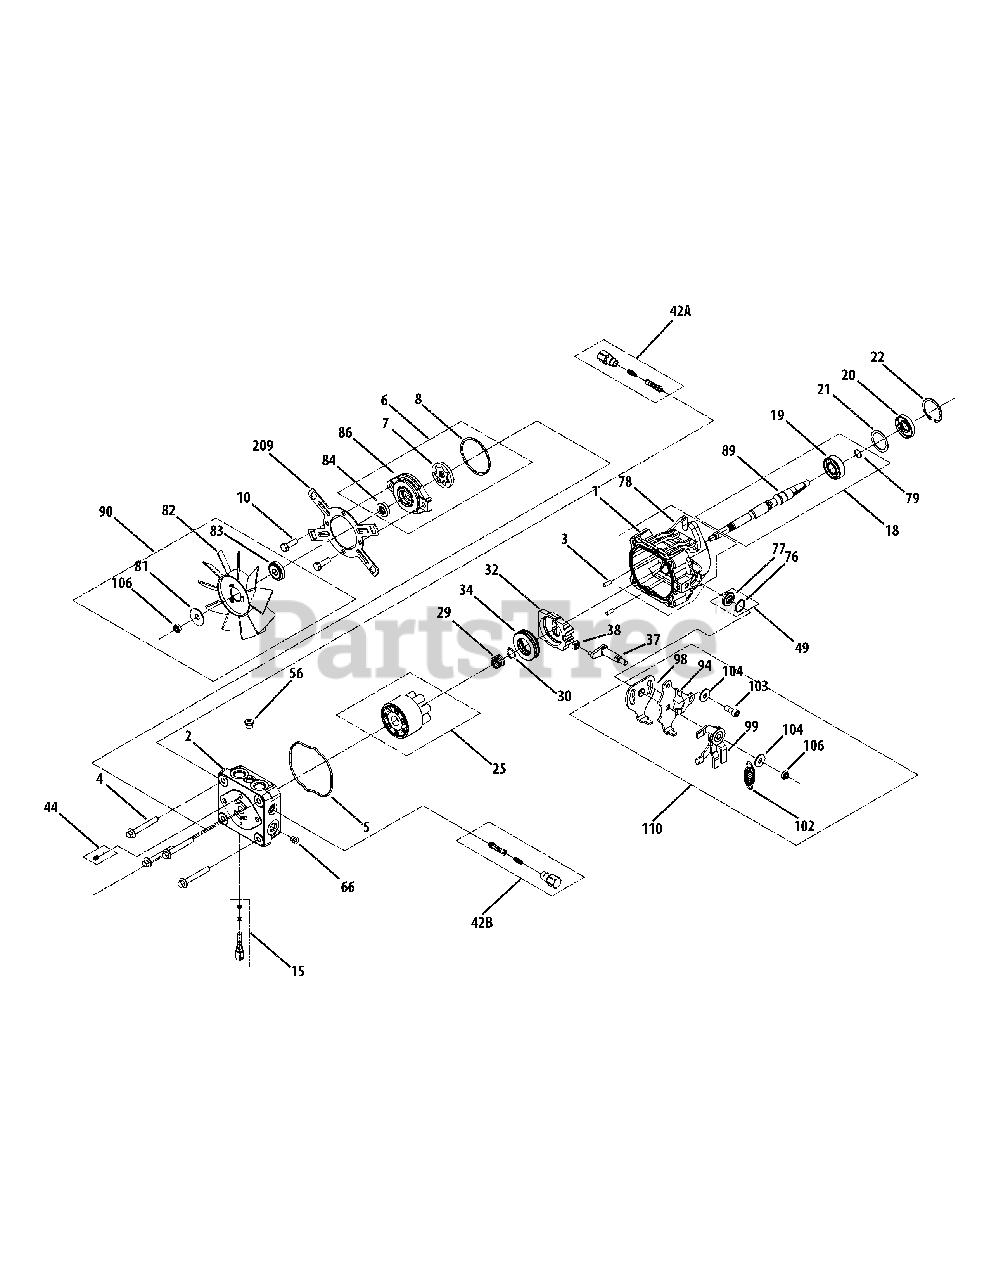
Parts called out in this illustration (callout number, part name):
1	Kit, Housing
1	Housing, Pump
2	Kit, Endcap
2	Plug 9/16-18 (Metal)
3	Straight Headless Pin
4	Hex Bolt M8-1.25 x 60mm Long
5	Housing, O-Ring
6	Kit, Charge Pump
6	Gerotor
6	O-Ring
6	Housing, Charge Pump
10	Screw, 5/16-18 x 1.00 Long
15	Kit, Bypass Valve
18	Kit, Pump Shaft
18	Bearing, Ball 17 x 40 x 12
18	Ring, Ret. Wire .561 I.D.
18	Shaft, Input Tapered Keyed
20	Lip Seal 17 x 40 x 7 PTC
22	Retaining Ring
25	Cylinder Block Kit
29	Block Spring
30	Block Thrust Washer
34	Ball Thrust Bearing
37	Arm, Trunnion Tapered Square
42A	Kit, Shock Valve
42B	Kit, Shock Valve
44	Charge Relief Kit
49	Trunnion Seal / Retainer Kit
49	Ring, Ret. -Star Wash 1.0
49	Seal, Lip 12 x 25 x 5
56	Plug - 7/16-18 Steel (Diagnostic)
90	Washer, .40 x 1.55 x .06
90	Fan, 6", 10 Blade
90	Fan Hub
100	Overhaul Seal Kit
100	O-Ring, Housing
100	O-Ring
100	Seal, Lip 17 x 40 x 7
100	Ring, Retaining
100	Seal, Lip 12 x 25 x 5
106	Nut, Lock, Side 5/16-24UNF-2B
110	Arm, Control
110	Arm, RTN
110	Assembly, RTN Bi-Directional
110	Spring, Extension (STD)
110	Screw, 5/16-24 x .75 (Patch)
110	Washer
110	Nut, Lock, Side 5/16-24UNF-2B
209	Bracket, Shroud
